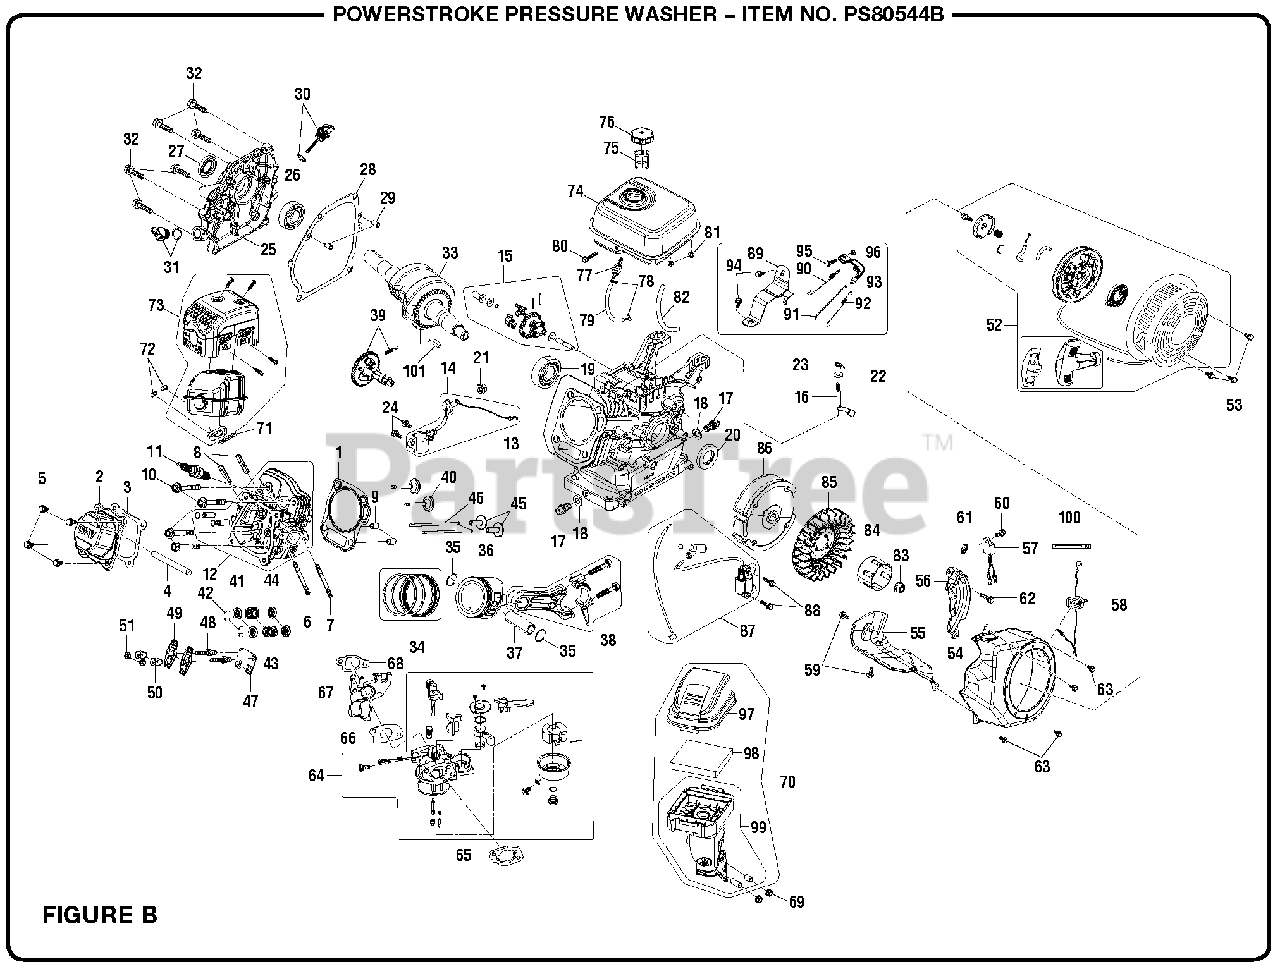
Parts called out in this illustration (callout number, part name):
1	Cylinder Head Gasket
2	Cylinder Head Cover Assembly
3	Cylinder Head Cover Gasket
10	Cylinder Head Bolt
12	Cylinder Head Assembly
13	Crankcase Assembly
14	Engine Oil Sensor
15	Governor Gear Assembly
17	Drain Plug Bolt
25	Crankcase Cover
28	Crankcase Gasket
30	Oil Dipstick Assembly
31	Engine Oil Plug Assembly
33	Crankshaft Assembly
34	Piston Ring Assembly
35	Piston Pin Clip
39	Camshaft Assembly
41	Valve Spring Seat
42	Valve Lock Clamp
47	Lifter Stopper Plate Assembly
48	Valve Adjusting Bolt
50	Valve Adjusting Nut
52	Recoil Starter Assembly
54	Shroud
55	Cylinder Body Shroud
58	Stop Engine Switch Assembly
64	Carburetor Assembly
65	Air Cleaner Gasket
66	Carburetor Gasket
67	Carburetor Insulator Plate
68	Carburetor Insulator Gasket
71	Exhaust Outlet Gasket
73	Muffler Assembly
76	Fuel Tank Cover
77	Fuel Tank Oil Outlet Assembly
86	Flywheel Assembly
87	Ignition Coil
89	Throttle Control Assembly
90	Governor Spring
92	Throttle Valve Returning Spring
93	Governor Support Assembly
95	Governor Support Bolt
97	Air Cleaner Case Cover
98	Air Cleaner Element Assembly
99	Air Cleaner Elbow Assembly
